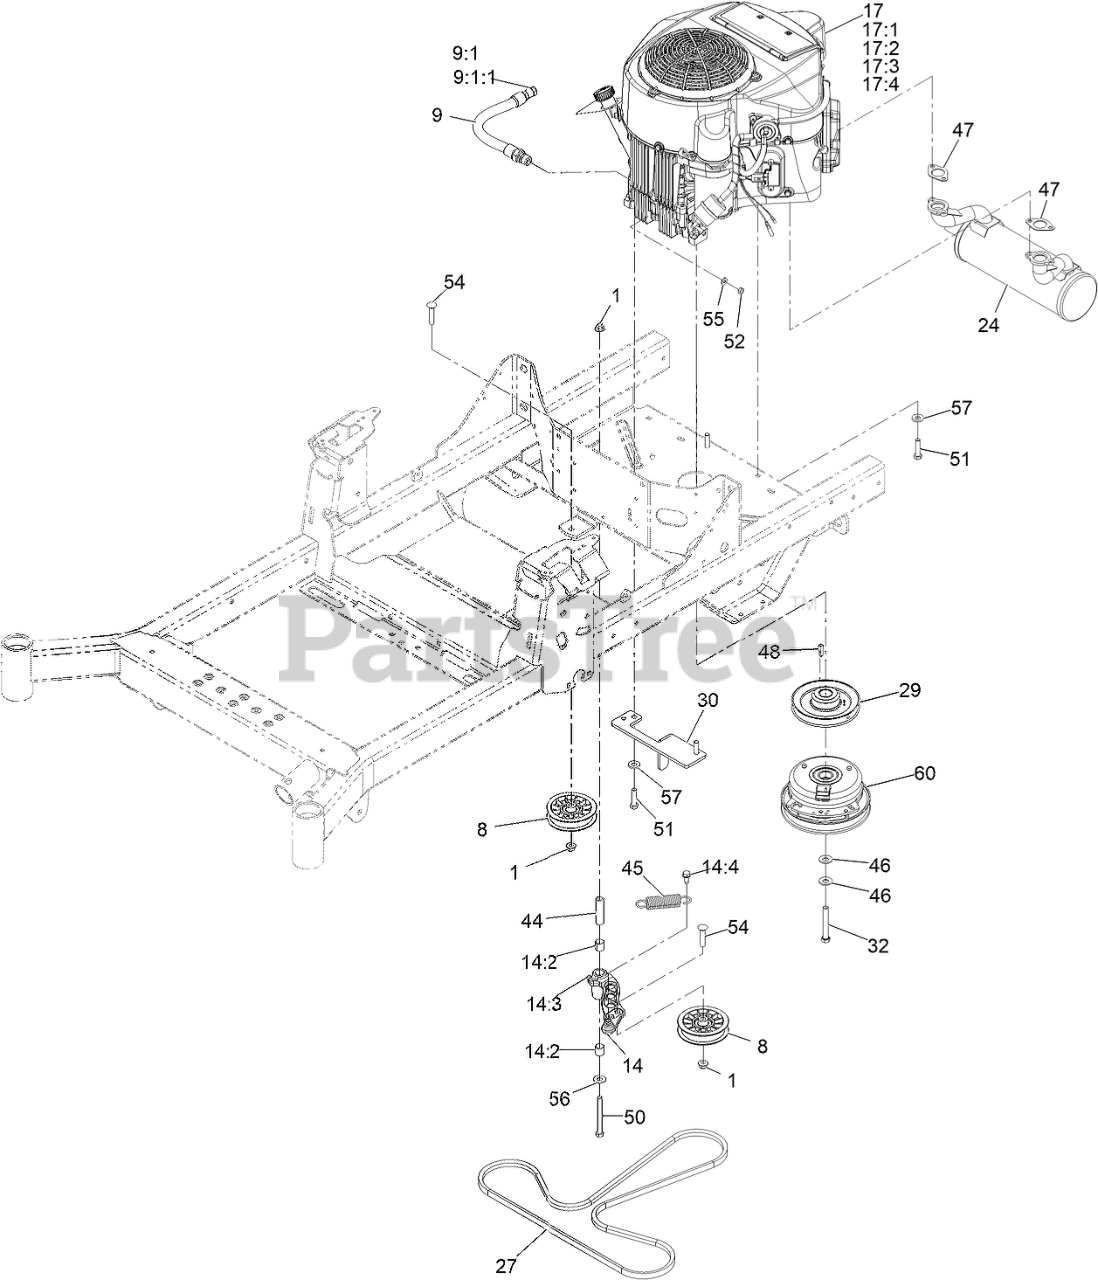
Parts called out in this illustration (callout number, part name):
1	NUT-HF, NI
8	PULLEY-FLAT IDLER
9	ENGINE OIL DRAIN HOSE ASM
9:1	PLUG-HH
9:1:1	O-RING
14	IDLER ARM ASM
14:2	SLEEVE-BEARING
14:3	FITTING-GREASE, 90 DEG
14:4	SCREW-THD ROLL, HWH
17:1	Kawasaki 49065-7007 Engine Oil Filter
17:2	Kawasaki 49019-7005 Fuel Filter
17:4	Kawasaki 11013-7049 Engine Air Filter
24	MUFFLER
27	BELT-V
29	SHEAVE-ENGINE
30	ANCHOR-CLUTCH
32	SCREW-HH W/LOCTITE
44	BUSHING-PIVOT, IDLER
45	SPRING-EXTENSION
46	WASHER-SPRING
47	GASKET-EXHAUST
50	SCREW-HH
51	SCREW-HH
52	NUT-HEX
54	SCREW-CARR
55	WASHER-FLAT
56	WASHER-FLAT
57	WASHER-BELLEVILLE
60	CLUTCH - 1.00 HD
